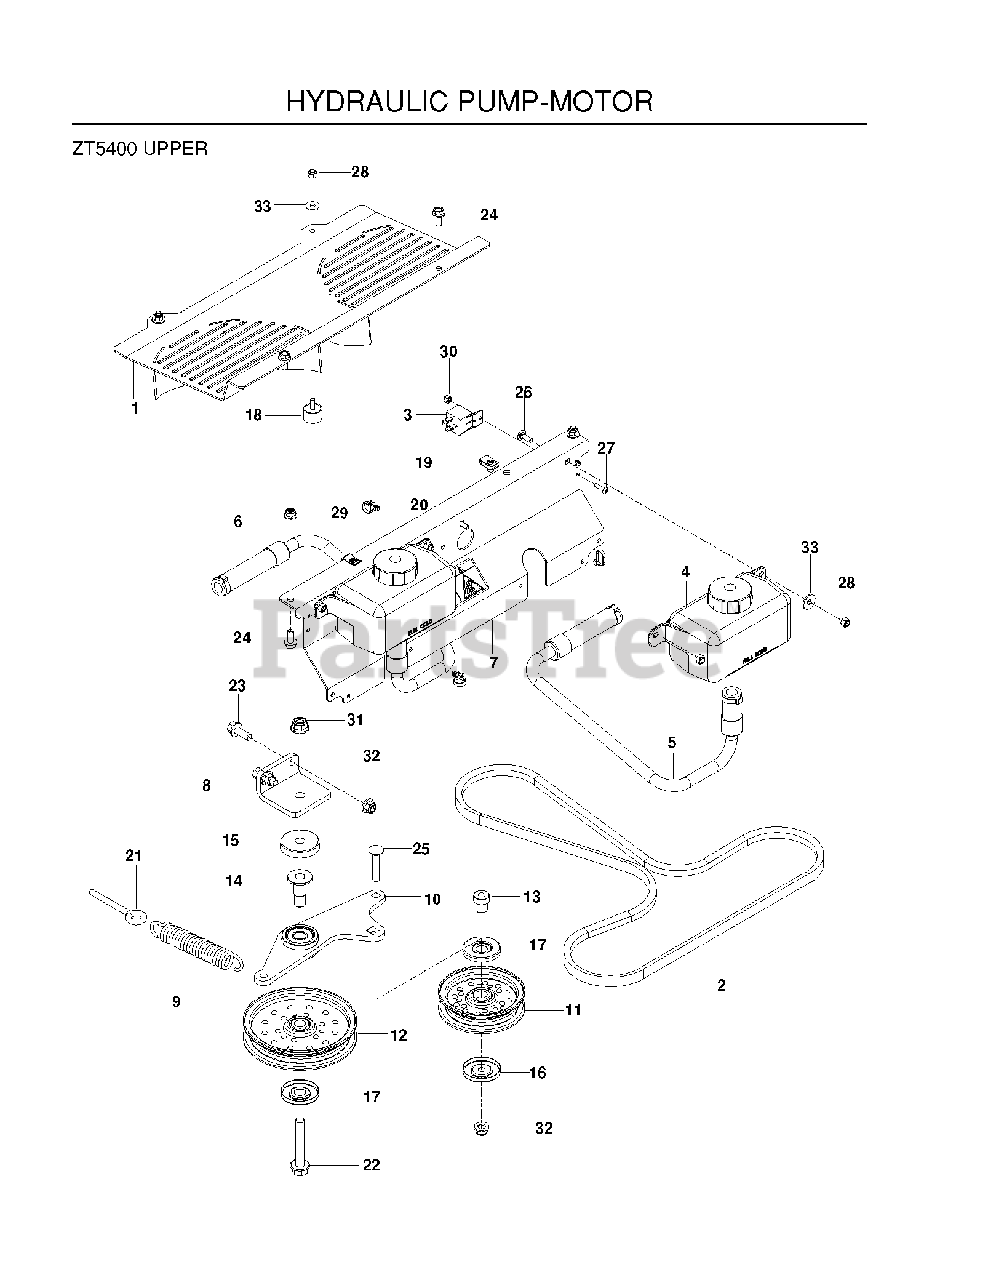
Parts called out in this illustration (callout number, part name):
11	IDLER PULLEY
12	IDLER, FLAT, 5.5"
13	PIVOT, IDLER
15	SHIELD, DUST
16	DUST SHIELD
17	SHIELD, DUST
18	BUMPER, MALE STUD, 1/4-20
19	U-CLIP 5/16-18 NUT RETAINER
21	EYE BOLT 5/16 X 3.50
22	HFFS 1/2-13 X 3 GD 5 ZD
23	HHFS 3/8-16 X 1 GRD 5 ZD
24	HHFS 5/16-18 X 3/4
25	RHSNB 3/8C X 2
26	RHSNB 1/4C X 3/4
27	SCR #10-24 X .75 SKT HD BLK
28	NUT 1/4-20 NYLOC
29	5/16-18 NYLOC FLANGE NUT
30	NUT 10-24 NYLOC
31	NUT, 1/2-13 HEX FLG NYLOC ZD
32	NUT 3/8-16 HEX FLG NYLOC ZD
33	WASHER 1/4 FLAT
